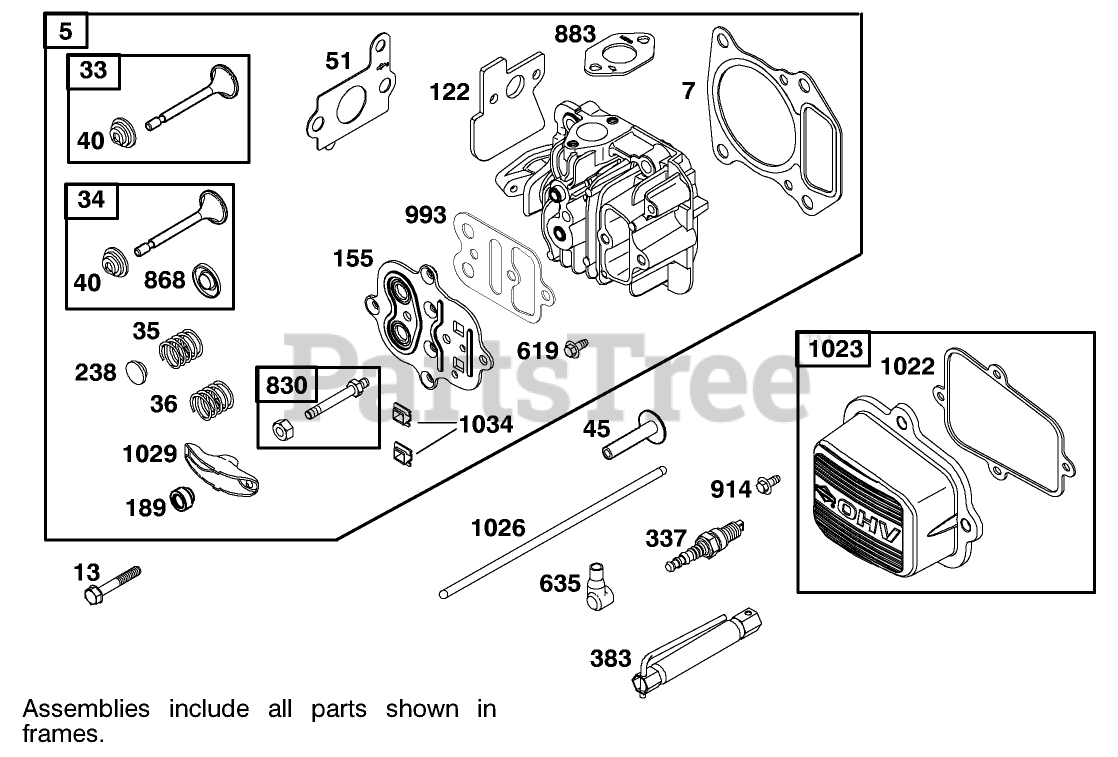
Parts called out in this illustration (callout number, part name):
5	Cylinder Head
7	Cylinder Head Gasket
13	Screw
33	Valve-Exhaust
34	Valve-Intake
35	Spring-Valve
36	Valve Spring (Exhaust)
40	Gear-Cam
45	Tappet-Valve
51	Gasket-Intake
122	Gasket-Intake
155	Cylinder Head Plate
189	Rocker Arm Ball
238	Cap-Valve
337	Sparkplug
383	Wrench-Spark Plug
635	Sparkplug Boot
830	Rocker Arm Stud
868	Valve Seal
883	Exhaust Gasket
914	Screw (Rocker Cover)
993	Plate Gasket
1022	Gasket
1023	Cover?Rocker
1026	Push Rod
1029	Arm-Rocker
1034	Guide-Rod, Push
